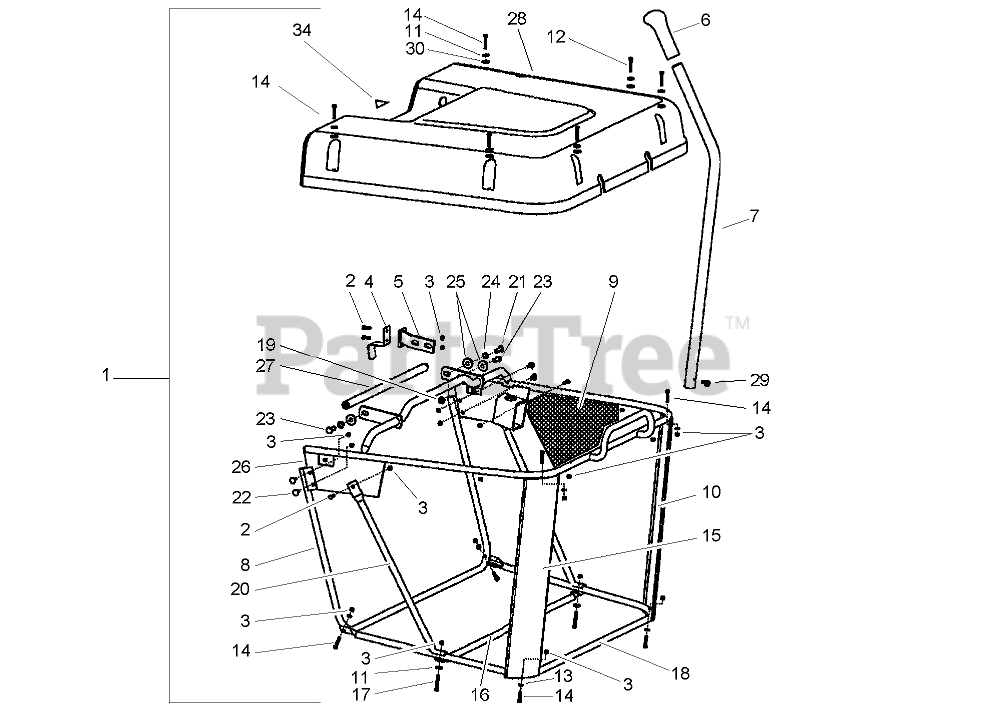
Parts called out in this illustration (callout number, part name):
1	COLLECTOR ASM
2	SCREW-HH
3	NUT-LOCK
4	SPRING-COLL, INTERLOCK SWITCH
5	Bracket-Spring
6	GRIP-HANDLE
7	LEVER-DUMP
8	FRONT FRAME ASM
9	BAG-GRASS
10	SUPPORT-CORNER, RIGHT
11	WASHER-FLAT
13	WASHER
14	SCREW-HEX
15	SUPPORT-CORNER, LEFT
16	BRACE-CONNECTING
17	SCREW-HEX
18	BOTTOM FRAME ASM
19	NUT-LOCK, NI
21	SCREW-HH
22	BOLT-CARRIAGE
23	SCREW-HH
24	WASHER-LOCK, SPRING
25	WASHER-PLAIN
26	TOP FRAME ASM
27	HANDLE-LIFT
28	Cover-Collector
30	WASHER-RUBBER
34	DECAL-BAG TO FRAME
